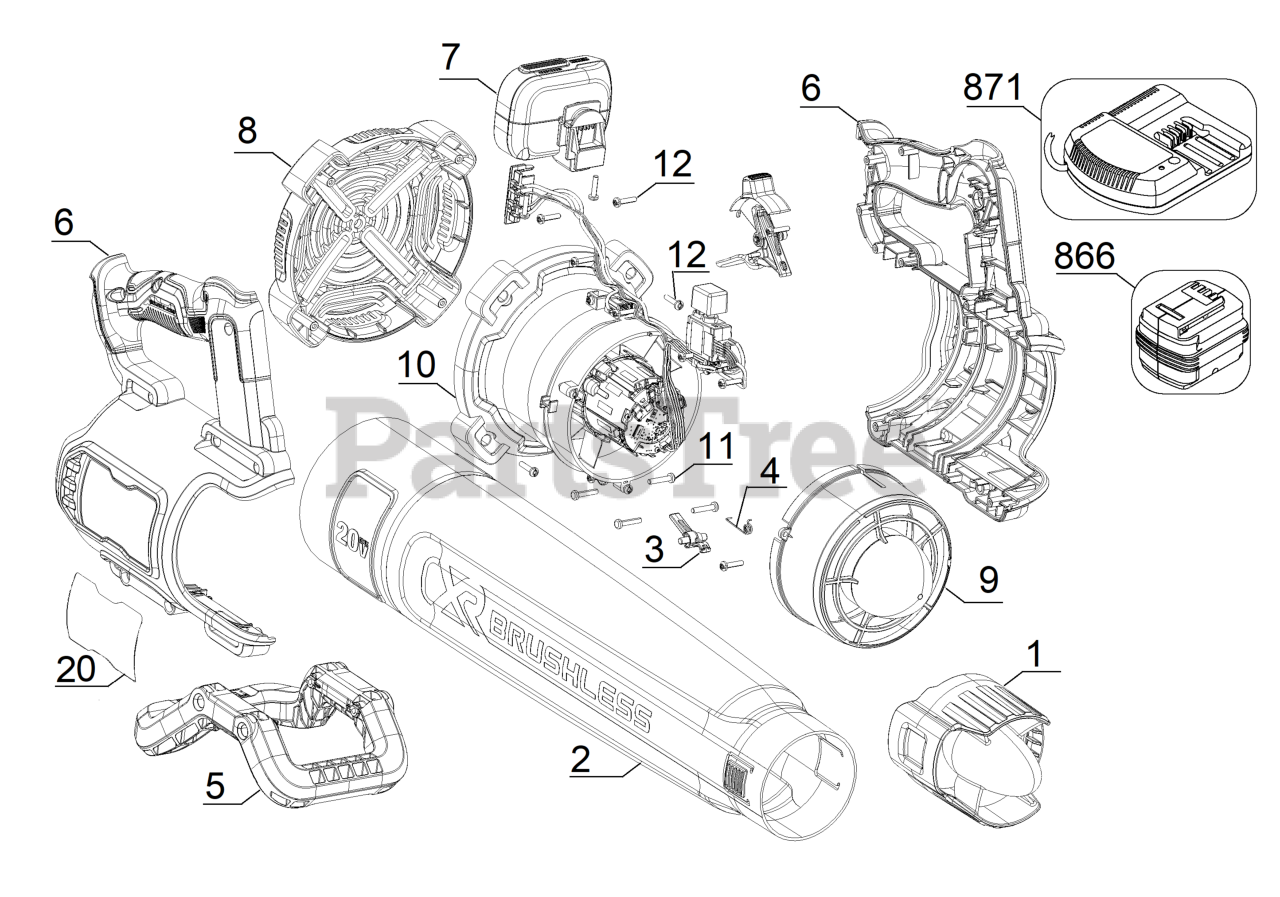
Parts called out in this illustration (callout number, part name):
1	AEROSPIKE ATTACH
2	BLOWER TUBE
3	TUBE LATCH
4	LATCH SPRING
5	LOWER GUARD SA
6	HOUSING PAIR
7	BATTERY RAIL
8	INLET GRILL
9	STATOR HOUSING
10	MOTOR (W/MODULE)
11	SCREW M3.5X19
12	SCREW
20	LABEL-RATING DCBL722
866	BATTERY
871	CHARGER
